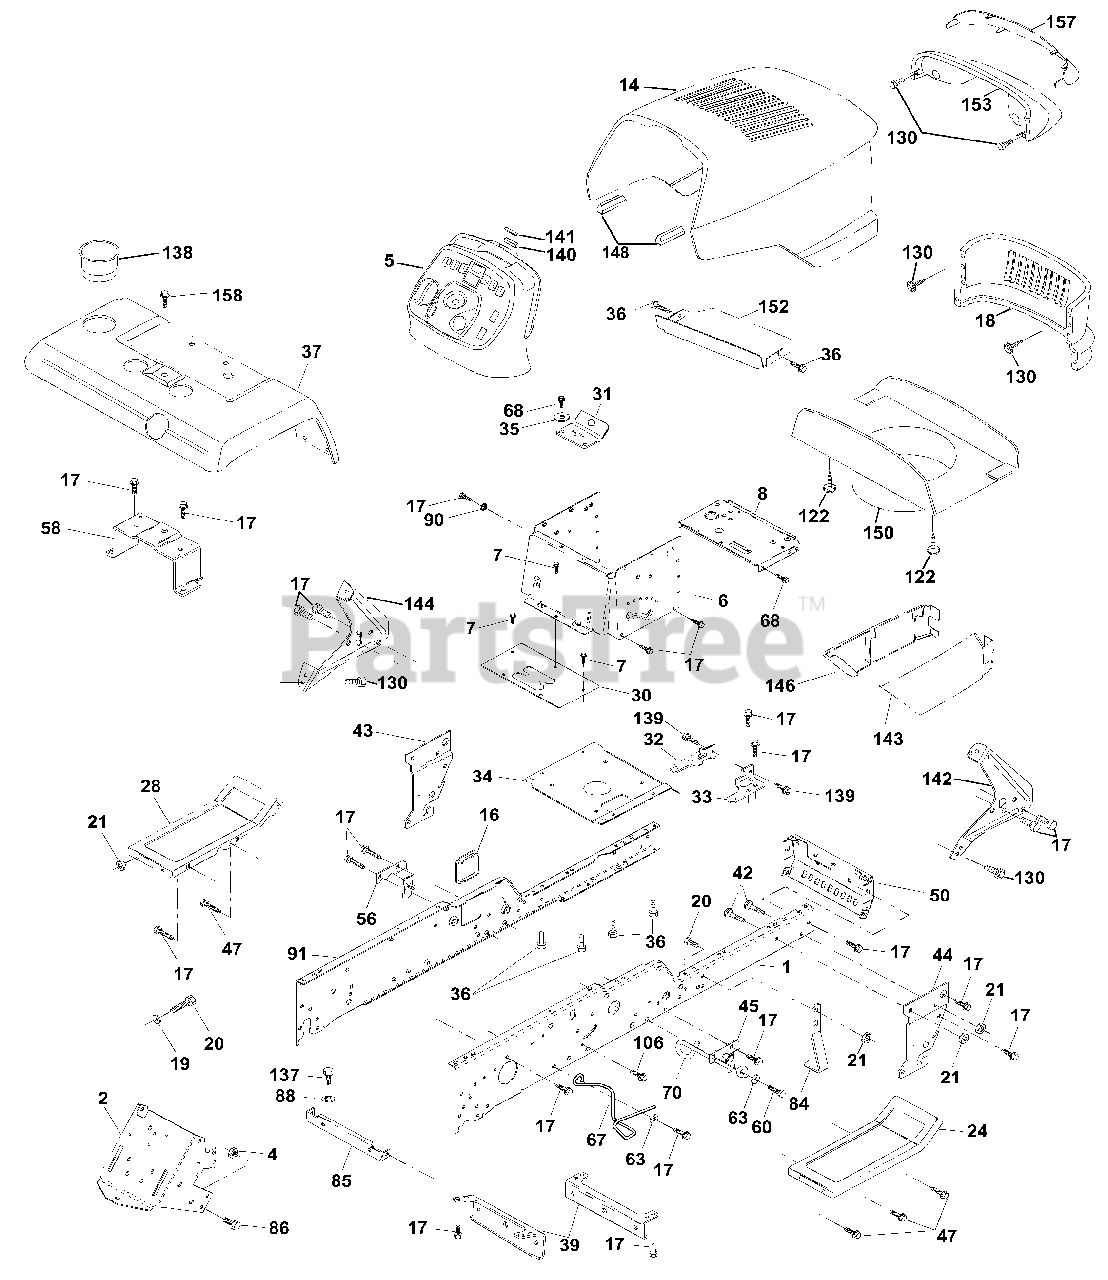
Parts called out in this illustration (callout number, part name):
1	Rail, Frame RH
2	Drawbar, Gt
4	Nut, Crownlock 7/16-14Unc
5	Dash
6	Dash Asm., Lower
7	Screw, Thd Cut 1/4-20 x 1/2
8	Support, Battery
14	Hood Asm., Pnt
16	Cover, Access
17	Screw, 3/8-16 x 3/4
18	Grille
19	Washer 13/32 x 13/16 x 12 Ga.
20	Bolt, Fin Hex 3/8-16 x 1
21	Nut, Crownlock 3/8-16 Unc
24	Footrest, RH
28	Footrest, LH
30	Saddle
31	Bracket, Supt 1-pc VGT Steering
32	Bracket, Pivot Chassis LH
33	Bracket, Pivot Chassis RH
34	Plate Asm Engine Chassis
35	Washer 11/32 x 11/16 x 16 Ga.
36	Screw 5/16-18 x 3/4
39	Bracket, Axle Front
42	Bolt, Carriage 3/8-16 x 1
43	Bracket, Spnsn Front Lh
44	Bracket, Spnsn Front Rh
45	Bracket Asm., Susp Chassis Rh
47	Screw Thdrol. 3/8-16 x 1/2
50	Bracket, Chassis Front
56	Bracket Asm., Susp Chassis Lh
58	Bracket Asm., Fender
60	Screw Thdrol 3/8-16 x 1-1/4
63	Washer 13/32 x 1 x 14 Ga.
67	Guide Belt Gear Dr.
68	Screw, Thd 5/16-18 x 1/2
70	Keeper Belt GD
84	Stop, Over Center Mower
85	Bracket Support Transaxle
86	Bolt, Fin Hex 7/16-14 Unc x 1
88	Washer Lock Hvy HLCL Spr. 7/16
90	Washer, Lock External Tooth 3/8
91	Rail, Frame Lh
106	Bolt 5/16-18 Type TT
122	Screw Hex Wshd 8-18 x 7/8
130	Screw HWHD Hi-Lo #13-16 x 3/4
137	Bolt Fin Hex 7/16-14 x 1 Gr. 5
138	Cupholder YTGT
139	Bolt Shoulder 5/16-18 TT
140	Magnet YTGT
141	Stricker Plate YTGT
142	Bracket Dash RH
143	Grille Skirt RH
144	Bracket Dash LH
146	Grille Skirt LH
148	Extrusion Bumper
150	Duct Heat Hood
152	Shield Browning
153	Lens Asm HL Bar
157	Lens Bar
158	Screw Thdrol 3/8-16 x 1/2 TYT
